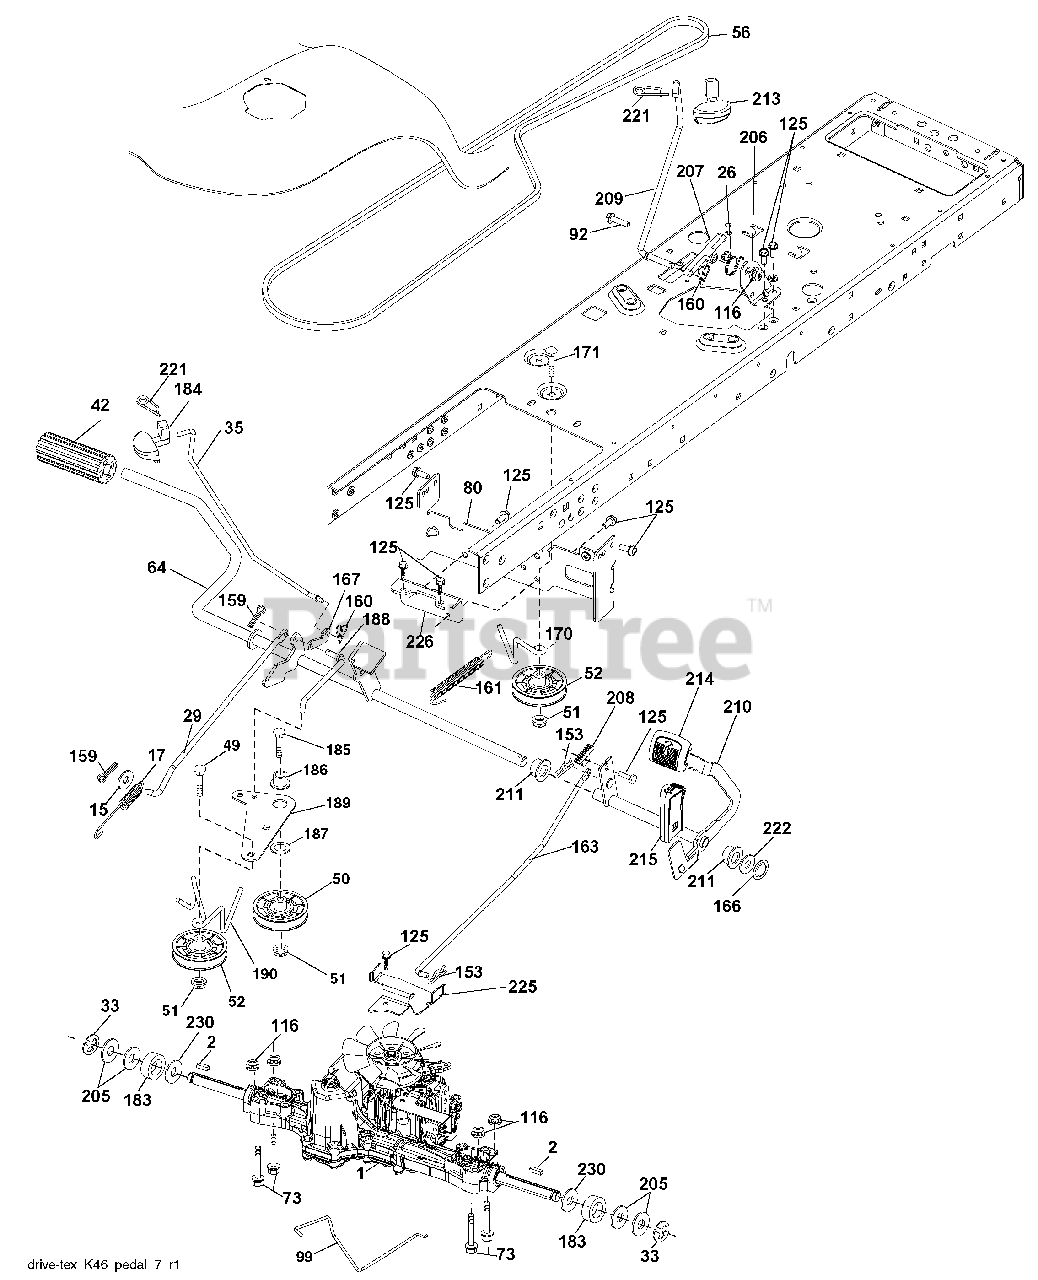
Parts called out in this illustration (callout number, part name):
1	Transaxle, Tufftorq K46BT
2	Key
15	Washer 13/32 x 13/16 x 16 Ga.
17	Spring, Brake
26	Spring Return Cruise
29	Rod, Brake
33	Ring E
35	Rod, Brake, Park
42	Cover, Foot Pedal
49	Bolt
50	Pulley Idler Flat
51	Lock Nut 3/8-16
52	Idler V-Groove 910" Offset
56	V-Belt, Drive
64	Shaft Asm. Pedal Brake Control
73	Bolt Hex 5/16-18 x 3.75
80	Bracket Strap Torque
92	Bolt Fin Hex 5/16-18 unc x 1.25
99	Rod Spring Bypass
116	Nut Lock Hex Flange 5/16-18
125	Screw 5/16-18 x 3/4
153	Retainer Spring
159	Pin Cotter 1/8 x 3/4
160	Retainer Clip
161	Spring, Return, Clutch
163	Rod Pedal Control
166	Nut Push .625
167	Latch Brake Parking
170	Keeper Belt Centerspan
171	Bolt
183	Spacer Axle
184	Handle Parking Brake
185	Bolt
186	Spacer Retainer
187	Washer
188	Link Clutch Ground Drive
189	Bellcrank Ground Drive
190	Keeper Bellcrank Ground Drive
205	Washer 25/32 x 1-5/8 x 16 Ga.
206	Bracket Mount Latch Cruise
207	Latch Control Cruise
208	Gear Sector Control Cruise
209	Rod Control Cruise
210	Rockr Asm. Pdeal Control
211	Bearing Nylon
213	Knob control Cruise
214	Pad Pedal Forward
215	Pad Pedal Reverse
221	Retainer Spring Clip Handle
222	Washer 21/32 x 1-1/4 10 Ga.
225	Keeper Belt Transaxle
226	Bracket Mount Torque
230	Washer Harden .793 x 1.637 x .060
